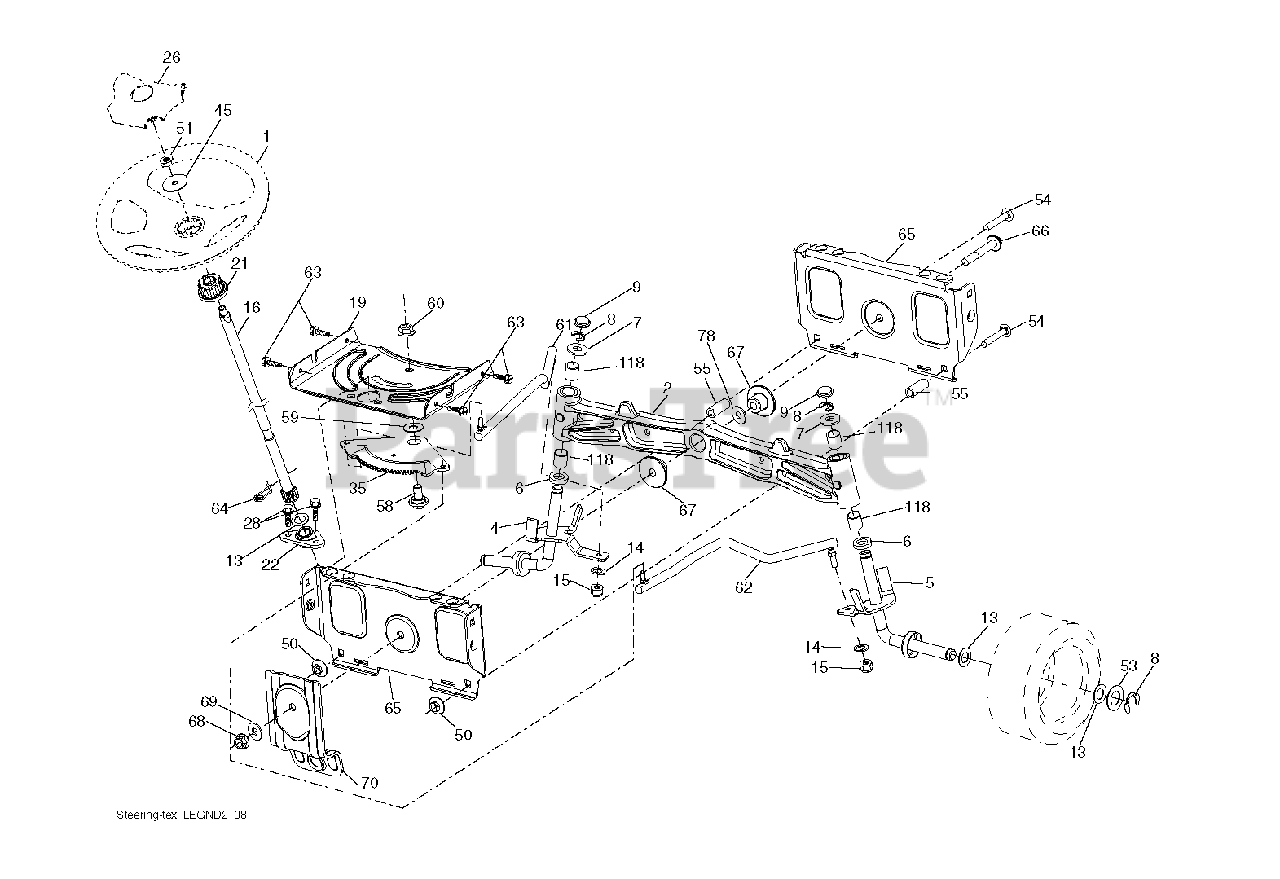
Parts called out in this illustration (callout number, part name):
1	WHEEL.STEER.HUSQ.SR.498.OVMLD
2	AXLE.SVC.ASM CAST IRON.TEX
4	SPINDLE.WELDED.LH.16"TEX
5	SPINDLE.WELDED.RH.16"TEX
6	THRUST WASHER
9	CAP.SPINDLE.BLACK
14	WASHER, LOCK 3/8
15	NUT CROWNLOCK 3/8-24
16	SHAFT.STEER.STEALTH.DD
19	PLATE.STEER.DDL.NLT/NG
21	ADAPTER, WHEEL STNG..
22	STEERING.SUPT.LOWER.
26	INSERT.CAP.WHL.STRG.HUSQ.PREM
28	SCREW, 3/8-16X3/4
35	GEAR.SECTOR.PLATE.DDL.
45	WASHER 9/16"ID, 2 3/8"OD
50	NUT LOCK FLG 3/8-16 UNC
51	NUT.HEX.1/2-20
53	WASHER.HARDENED
55	SPACER.BRACE.AXLE
58	BOLT.SHOULDER.SECTOR.P
59	WASHER.THURST.SECTOR.S
60	NUT FLANGE LOCK 5/8-11
61	DRAGLINK.LH.BALLSTUD.D
62	DRAGLINK.RH.BALLSTUD.D
63	SCREW
64	RETAINER.CLIP.SPRING.S
65	BRACE.AXLE.FRONT.NLT/N
66	BOLT HEX FGHD 7/16-14 X 3 SERR
67	BUSHING.PM.FRONT AXLE
68	NUT.LOCK.FLANGE.7/16
69	WASHER.1.5X.505X.118
70	BRKT.DECK.SUSPENSION.F
78	THRUST WASHER
118	BUSHING, AXLE CAST
